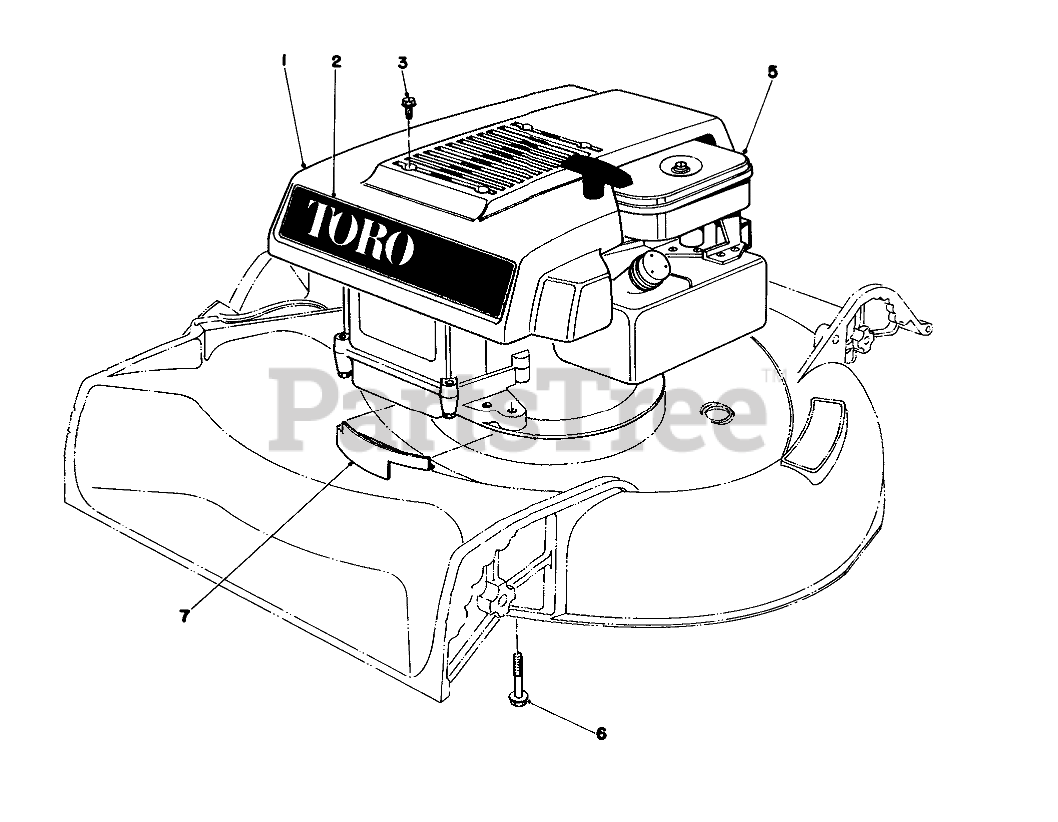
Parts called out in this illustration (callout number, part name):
1	SHROUD
2	Decal-Toro
3	8X1/2 SELF TAP SCREW
5	Engine (Model 16067)
6	3/8-16 X 2-3/4 CAPSCR
7	HOUSING CAP
